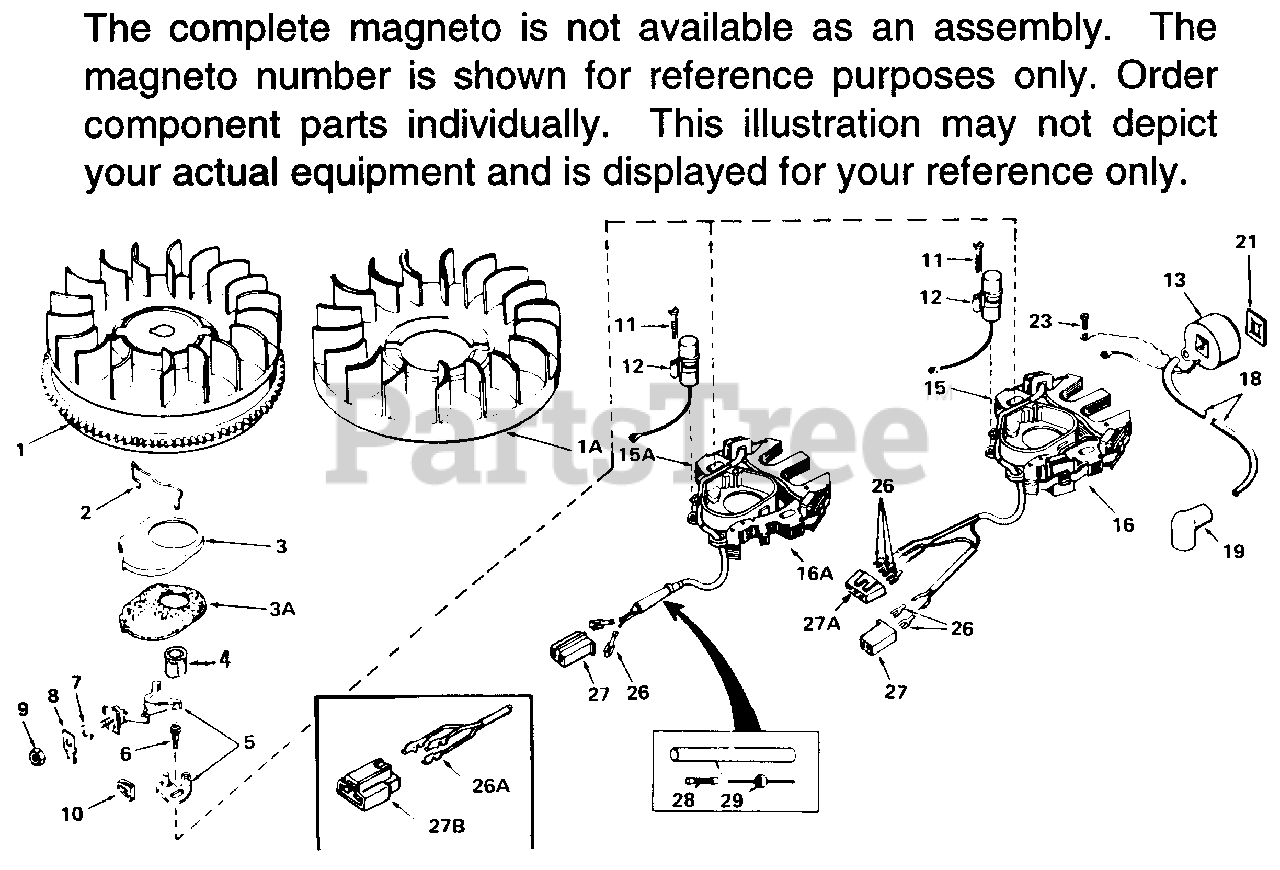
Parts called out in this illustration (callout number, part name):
1	Flywheel (Incl. 1A)
2	Spring, Dust cover
3	Cover, Dust
3A	Gasket, Dust cover
5	Breaker Points (also available in Pac kaged Part #740037B)
6	Screw & Lockwasher
7	Washer, Terminal
8	Tab, Terminal
9	Nut, Terminal
10	Felt, Cam wiper
11	Screw, Condenser fastening
12	Condenser
13	Coil Assy. (Incl. 18)
15	Stator Plate Assy. Incl. 2 thru 13, 1 6, 19, 21& 23
16	Core & Generating Assy. Incl. 26,27, 27A
18	Wire, Lead
19	Cover, Spark plug
21	Clip, Coil fastening
23	Screw, Ground terminal
26	Terminal, Female
27	Connector
27A	Connector, Flat
